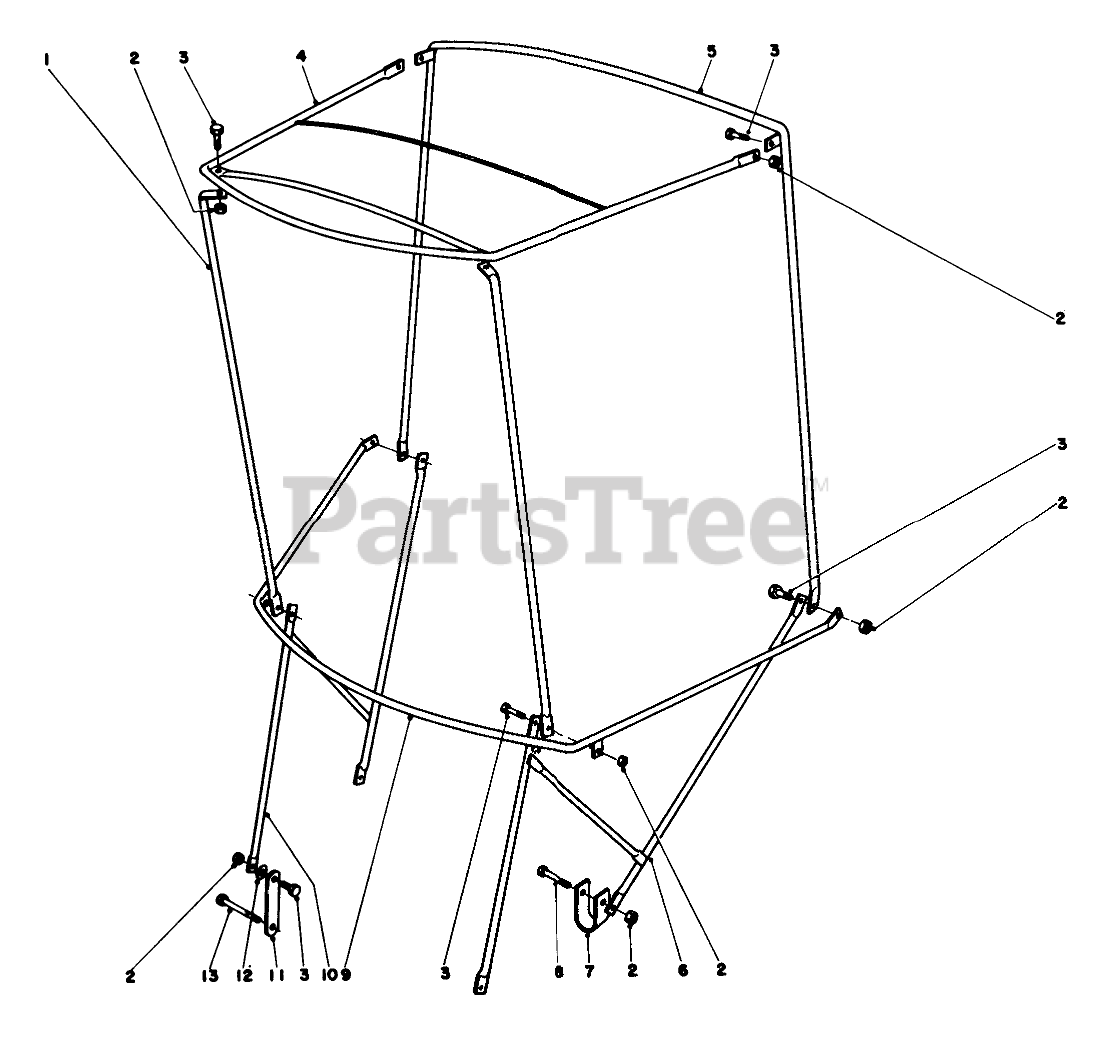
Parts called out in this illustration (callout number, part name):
2	NUT-LOCK
3	SCREW-HH
4	FRAME-TOP
5	BOW-VERTICAL, REAR
6	Attaching Bracket, L.H.
7	U CLAMP
8	SCREW-HH
9	BOW-CURVED
10	Attaching Bracket, R.H.
11	Mounting Strap
12	WASHER-LOCK/EXT
13	SCREW-HH
